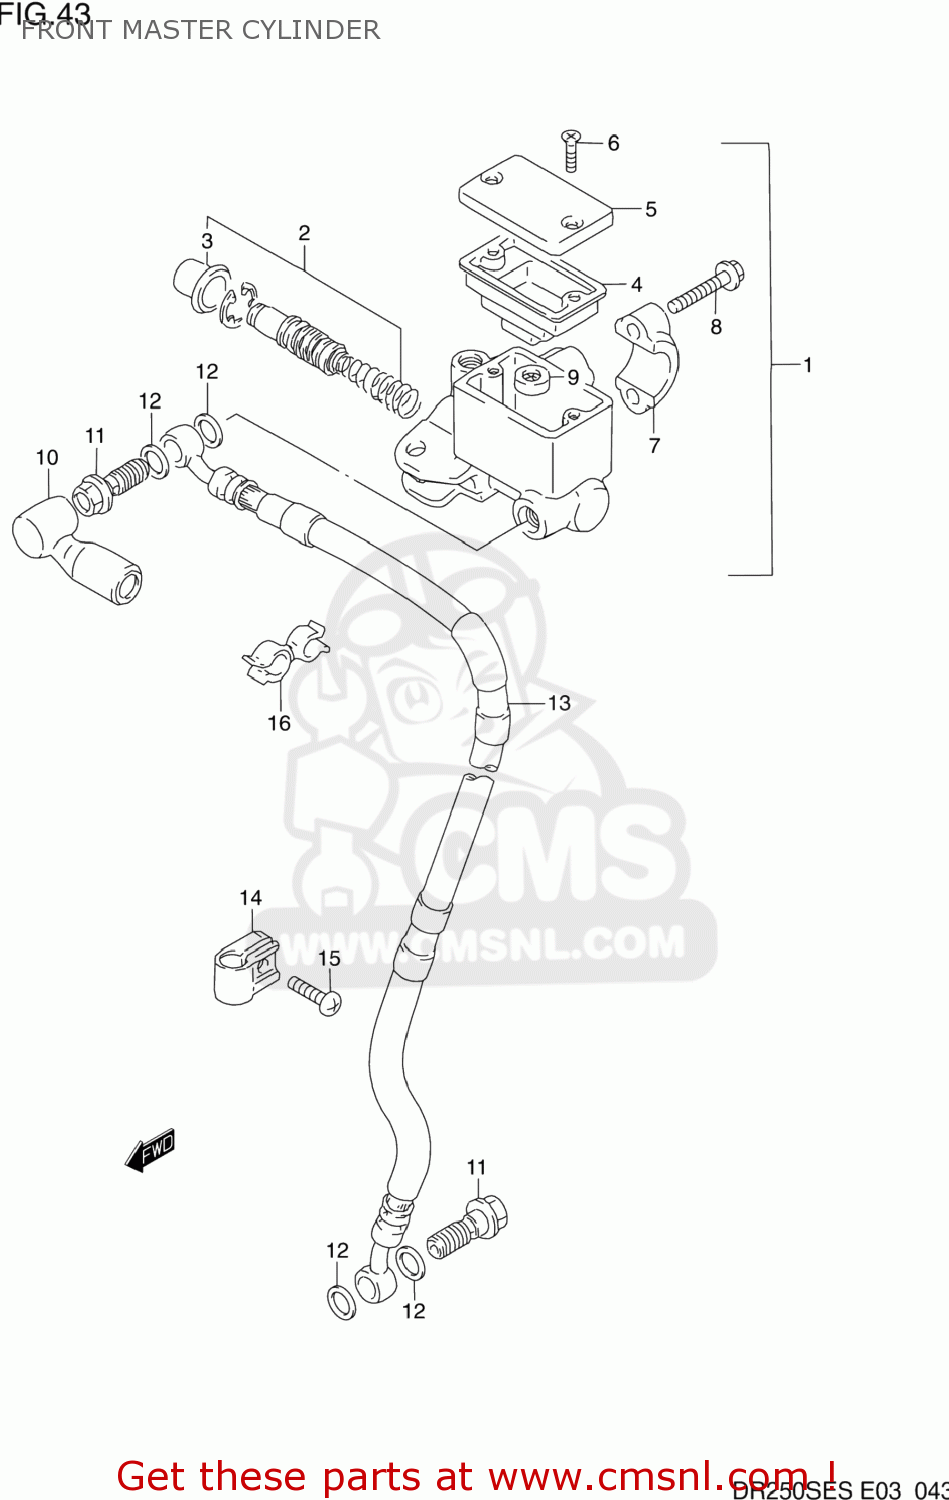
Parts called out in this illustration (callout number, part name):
1	CYLINDER ASSEMBLY,FRONT MASTER
2	PISTON/CUP SET
3	BOOT
4	DIAPHRAGM
5	CAP
6	SCREW
7	HOLDER
8	BOLT
9	SEPARATOR
10	BOOT,MASTER CYLINDER
11	BOLT UNION
12	WASHER(10X15X1.5)
13	HOSE,FR BRAKE
14	CLAMP,BRAKE HOSE
15	SCREW
16	CLIP
